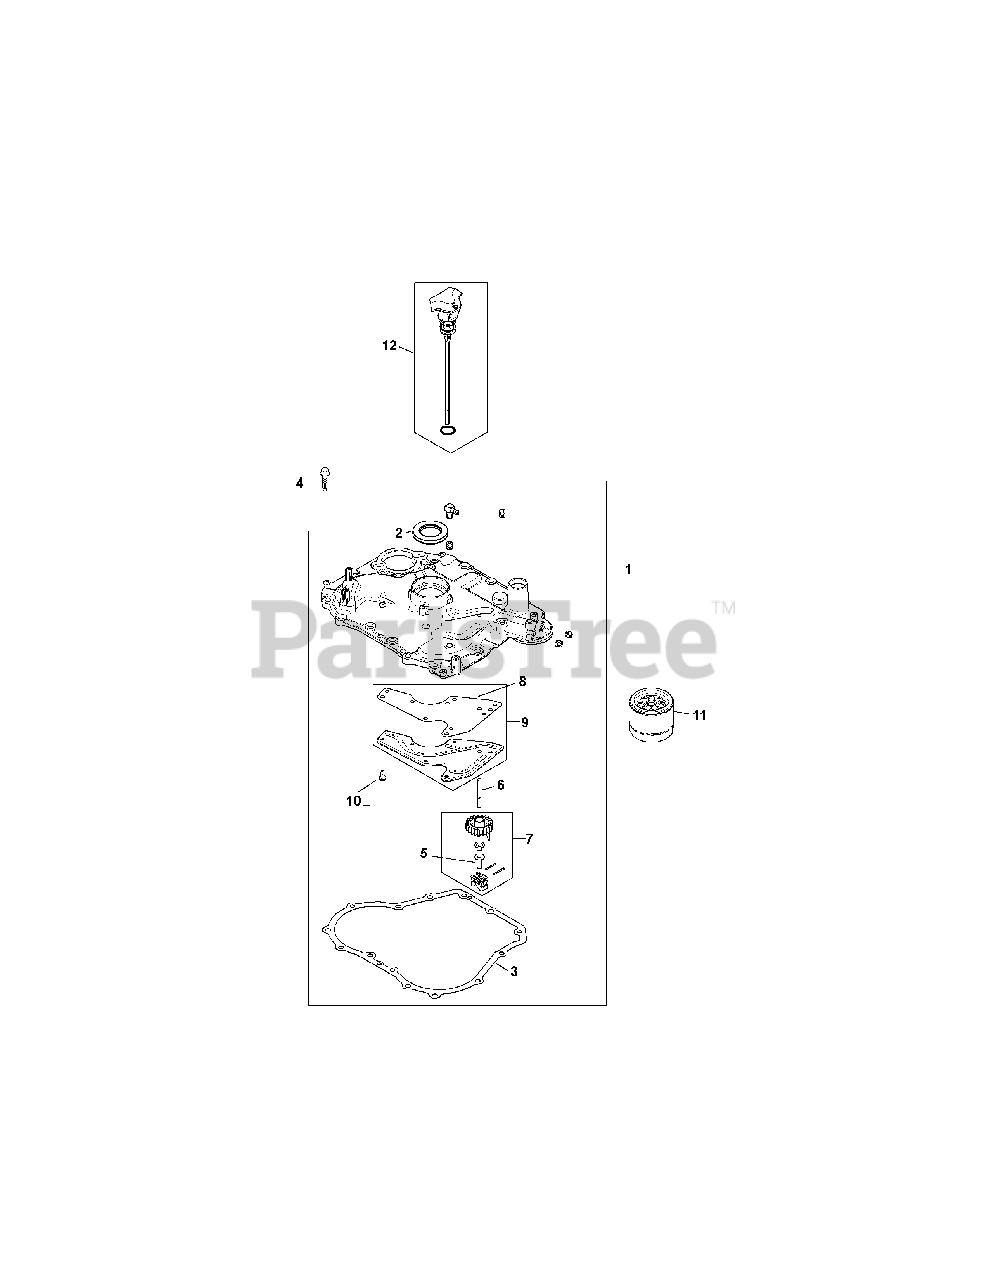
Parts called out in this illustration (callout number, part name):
1	Closure Plate Assembly
3	Closure Plate Gasket
4	Hex Flange Screw, 1/2
5	Governor Regulating Pin
6	Governor Cross Shaft
7	Governor Gear Assembly
8	Oil Passage Gasket
9	Oil Passage Cover Kit (Includes 7)
10	Flg. Thd. Frm. Screw, M5 X 0.8 X 13
12	Dipstick Assembly Blade
